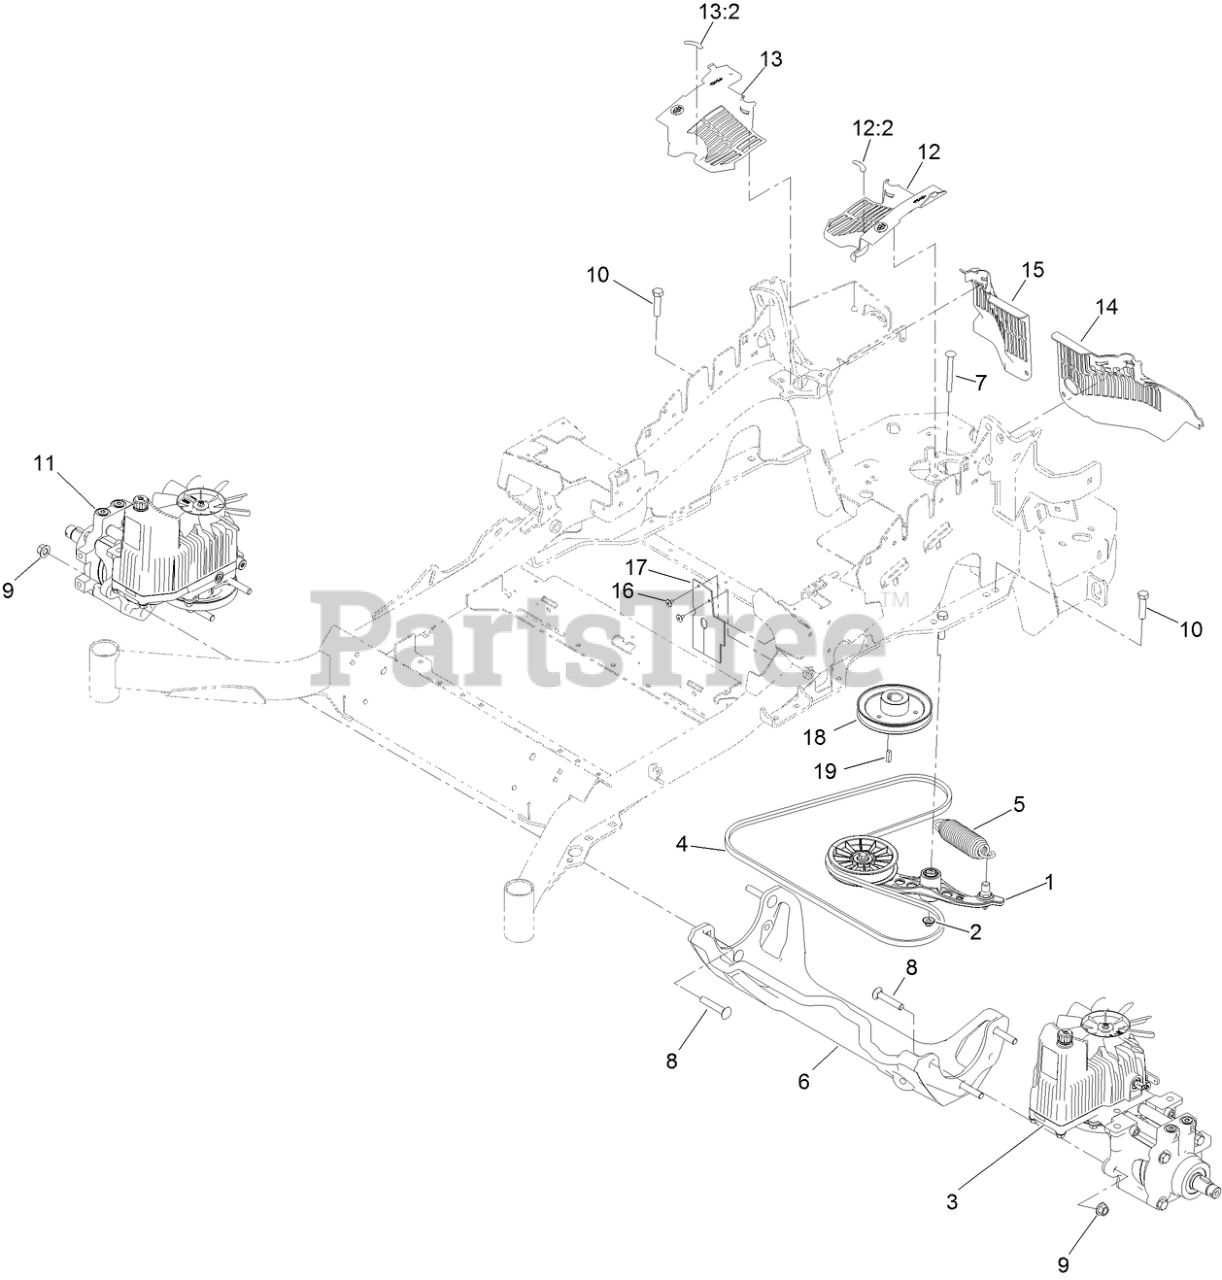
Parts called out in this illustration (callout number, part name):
1	PUMP IDLER ASM
2	NUT-FLANGE, NI
3	HYDRO-LH
4	BELT-V
5	SPRING-EXTENSION
6	CRADLE-HYDRO
7	BOLT-SHOULDER, CARRIAGE
8	SCREW-CARR
9	NUT-LOCK
10	SCREW-HH
11	HYDRO-RH
12	LH HYDRO GUARD ASM
12:2	DECAL-OIL, HYDRO
13	RH HYDRO GUARD ASM
13:2	DECAL-OIL, HYDRO
14	GUARD-HYDRO, REAR (LH)
15	GUARD-HYDRO, REAR (RH)
16	RIVET-POP
17	DEFLECTOR-AIR FLOW
18	SHEAVE
